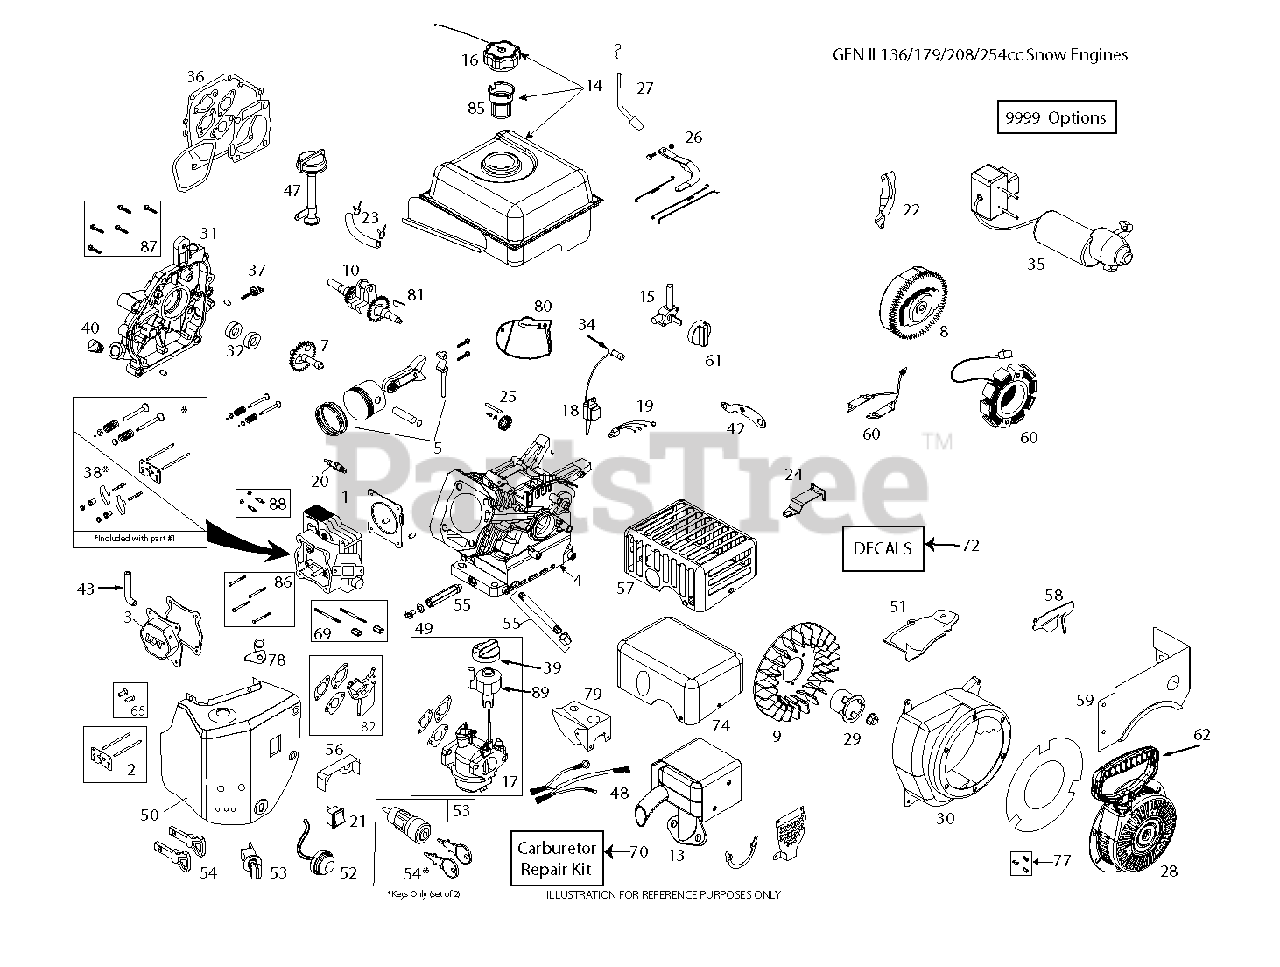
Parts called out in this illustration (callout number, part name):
1	CYLINDER HEAD ASSY.LCT.208
2	KIT.PUSH.ROD.SRV(SK208-1001)
3	VALVE COVER ASSEMBLY
8	FLYWHL.ASSY.MANUL.SK2081700
9	KIT.COOLNG.FAN.SERV(SK208-4000
10	CRANKSHAFT KEYED LCT 179
13	MUFFLER.ASM.LCT.208CC.SS
17	CARB.ASM.SS/SNO.LCT(SKSNO313)
18	208CC IGN COIL (STD)
20	SPARK.PLUG(2083810)
22	SHIELD.FLYWHEEL.ELEC.STRT.208C
23	KIT.FUEL.HOSE.208CC.SING/STAGE
24	SPEED.CTRL.BRKT.(SKSN0150)
25	GOVENOR.GEARS ASM(SK2082900)
26	CARBURETTOR GOVERNOR LINK.ASM.
27	KIT.GOVERNOR.CRANK(SK208-3100)
28	STARTER.RECOIL.S/S SNO.78".ROP
29	STRTER.CUP(NON-SLOT)SKSN0601.2
30	BLOW.HSG.ASSY.ELEC(SKSN-0612)
31	COVER CRANKCASE.LCT.SK2083605
32	SEAL KIT (2 PCS)
34	SPARK.PLUG.BOOT.SNW,SKSN4691.1
36	GASKET.KIT.208CC(SK2084300.1)
37	DIPSTICK SMALL
38	ROCKER ARM KIT
40	NON REMOVABLE PLUG
43	TUBE.BREATHER.LCT.208
47	TUBE HIGH OIL FILL LCT 179
48	HARNESS.WIRE.SINGLE.STAGE.LCT
49	KIT.OIL.DRAIN.PLUG(SK2089911
52	BULB.FUEL.PRMR.W/HOSE(SKSNO306
53	SWITH.KEY.ASSEM.SNOW.SINGLE.ST
54	KEY SET(2 KEYS) SKSN0407.1
56	SHIELD.VAPOR.SNOW
62	STARTER.GRIP.SNOW.LCT.SKSN0603
65	TAPPET.KIT.LCT.208CC
69	CARB.STUDS & COUPLING KIT.SNOW
70	CARB.REPAIR.KIT.LCT.SK9900.1
77	BOLT.KIT.RECOIL.LCT.ALL.ENGINE
81	KEYS.FLYWHEEL.136/291CC.5PACK
82	SPACER.CARBURETOR.208CC.LCT
86	KIT.BOLT.CYLINDER.HEAD.(4PC)
86	STUD.MUFFLER.KIT.LCT
87	KIT.BOLT.CRANKCASE.COVER.6PC
91	Crankcase Cover Gasket
9999	High Altitude Jet for Beyond 6,000 Feet
